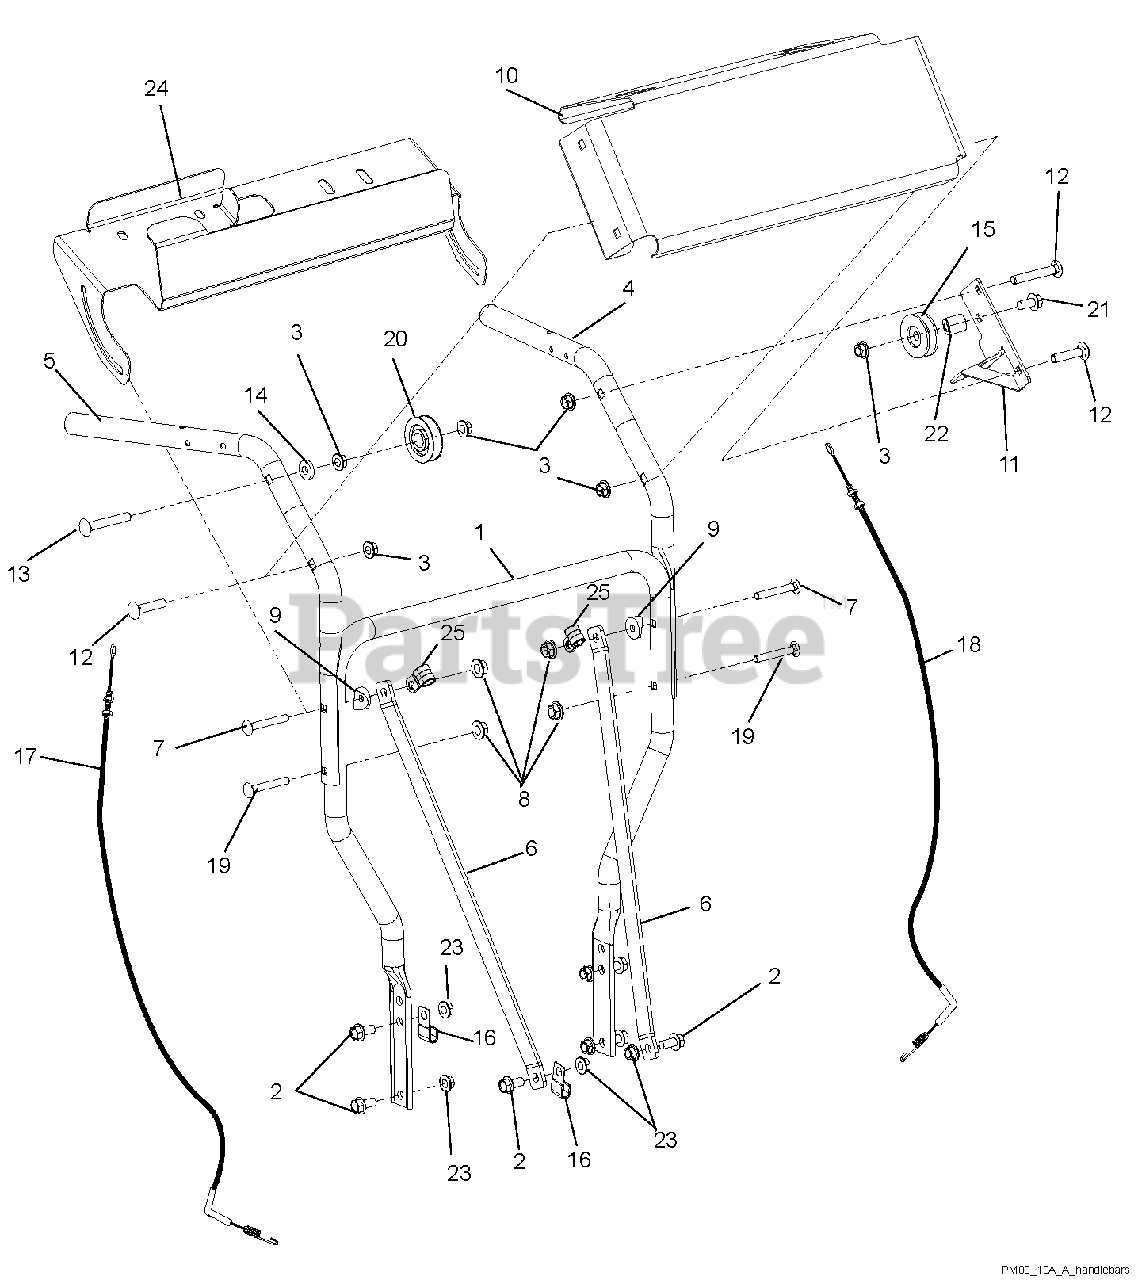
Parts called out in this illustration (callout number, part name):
1	HANDLEBAR, LOWER
2	BLT-SERHFWH .38-16X.75 YWZC
3	@NUT-LK-TOP-FLG .38-16 YWZC
4	WMT-HANDLEBAR, UPPER LH
5	HANDLEBAR, UPPER RH
6	BRKT-BRACE, HANDLEBARS
7	@BLT-RDHDSQNK .31-18X2.25 G5YZ
8	@NUT-LK-NYL-FLG .31-18 YWZC
9	SPACER, HANDLEBAR
10	DASH, WAW
11	MOUNT, WAW PTO CABLE (WLDMNT)
12	@BLT-RDHDSQNK .38-16X1.75 G5YZ
13	@BLT-RDHDSQNK .38-16X2.50 G5YZ
14	WSHR-FL-STL .406X1.00X.188 YWZ
15	IDLER, 3L FRONT SIDE .38X1.875
16	J-CLAMP
17	CABLE, WAW P-BRAKE
18	CABLE, WAW PTO
19	@BLT-RDHDSQNK .31-18X1.75 G5YZ
20	PULLEY, CABLE
21	@BLT-HEX .38-16X2.50 GR5 YWZC
22	SPACER, .437X1.0X1.23
23	NUT-LK-CTR-FLG .38-16 YWZC
24	BRKT, EMISSION COMPONENT MOUNT
25	CLAMP, CUSHIONED STEEL
